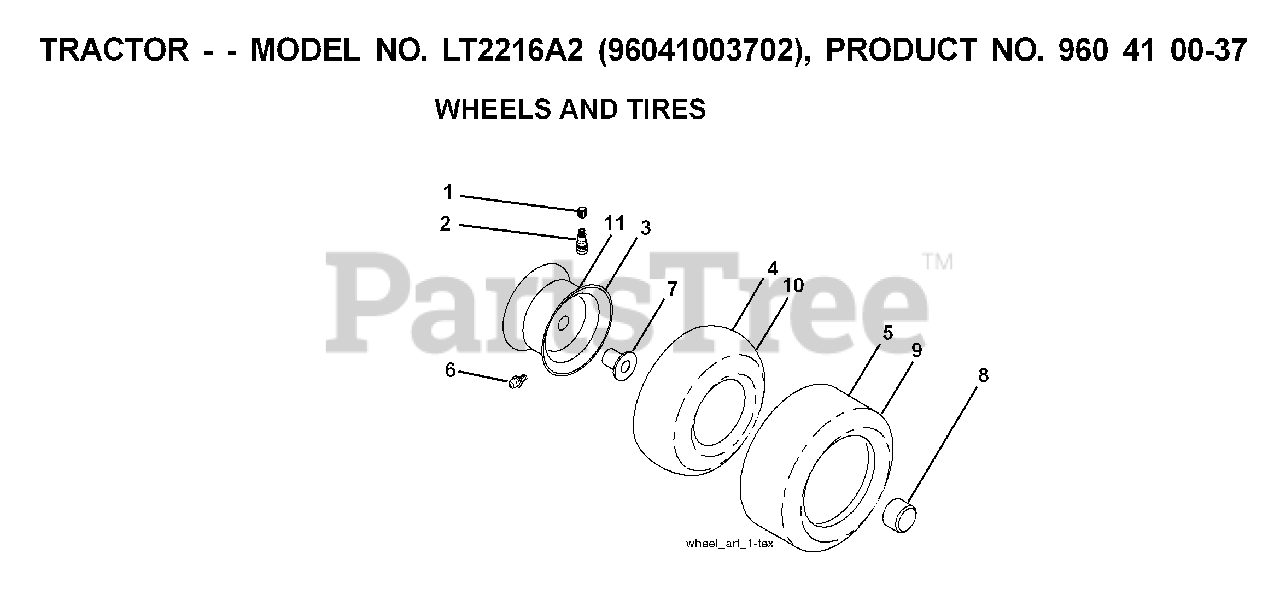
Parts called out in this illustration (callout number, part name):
1	VALVE CAP
2	VALVE STEM LT
3	RIM ASM 6" FRONT SILVER
4	TUBE.5.3/4.5/6
5	TIRE HEAVY DUTY
6	FITTING LT
7	BEARING T
8	CAP, AXLE BLK
9	TIRE.TS.20X10-8
10	TUBE
11	RIM ASM 8" REAR SILVER
